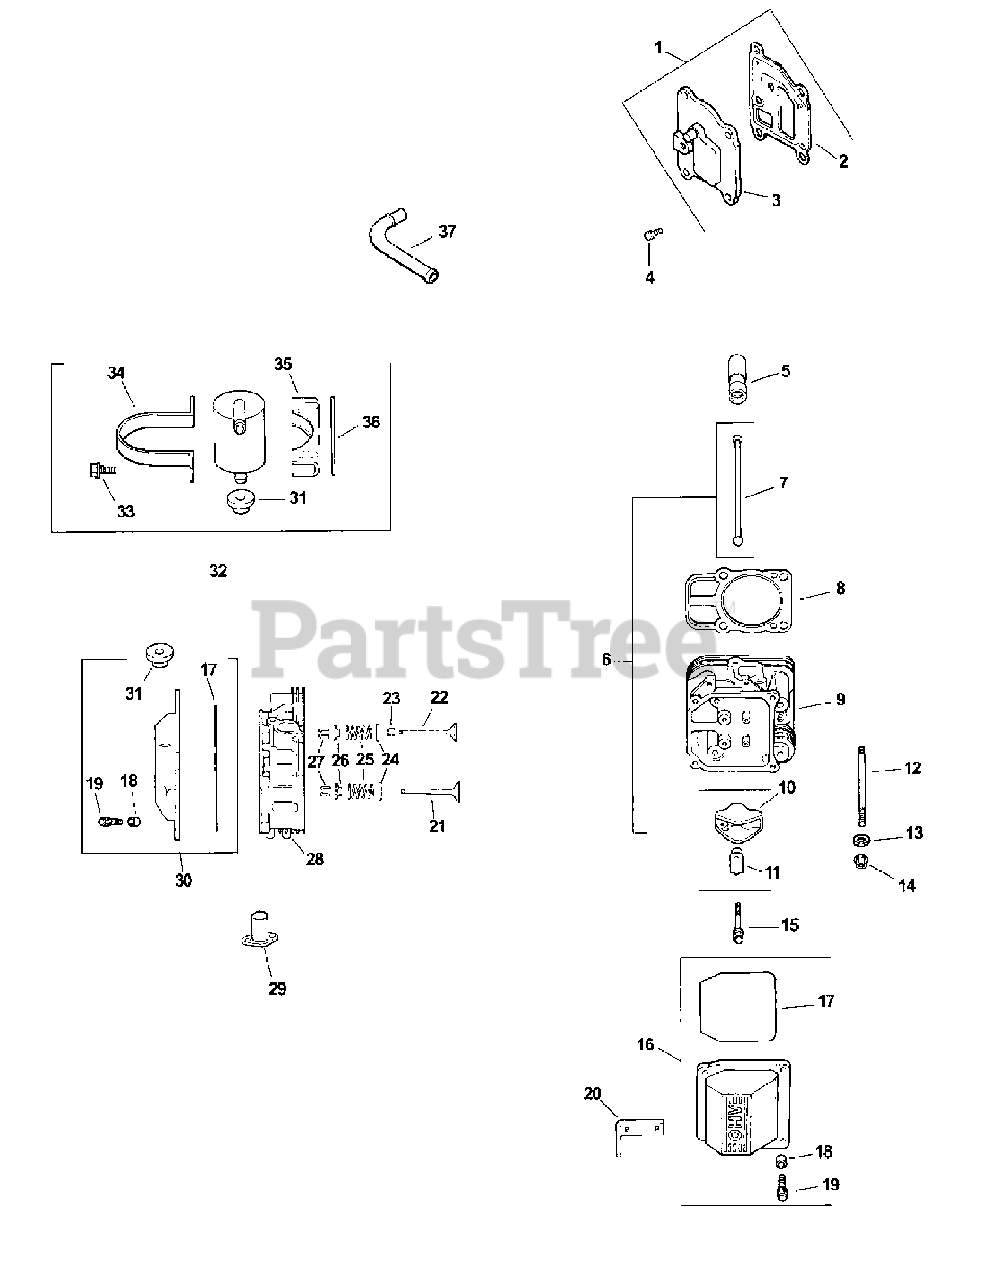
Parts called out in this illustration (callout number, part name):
1	Breather Cover w/Gasket Kit
2	Breather Gasket
3	Breather Cover
4	Hex Flange Screw (M6 x 1.0 x 20)
5	Valve Lifter
6	Valve Train Kit
8	Cylinder Head Gasket
9	Head Assembly # 2 Cylinder
11	Rocker Arm Pivot
12	Cylinder Head Stud
13	Flat Washer (1/4")
14	Hex Flange Nut (M8 x 1.25)
15	Hex Flange Screw (M6 x 1.0 x 34)
16	Valve Cover Kit
18	Spacer
19	Hex Flange Screw (M6 x 1.0 x 30)
20	Lifting Strap
21	Exhaust Valve (Std.)
21	Exhaust Valve (.025)
22	Intake Valve (Std.)
22	Intake Valve (.025)
23	Valve Stem Seal
24	Spring Retainer
25	Valve Spring
26	Valve Cap Spring
27	Retainer Kit
28	Head Assembly # 1
29	Exhaust Port Liner
30	Breather Valve Cover Kit
31	Rubber Grommet
32	Breather Seperator Kit
33	Hex Flange Screw (M5 x .8 x 16)
34	Breather Strap
35	Breather Seperator Bracket
37	Breather Hose
